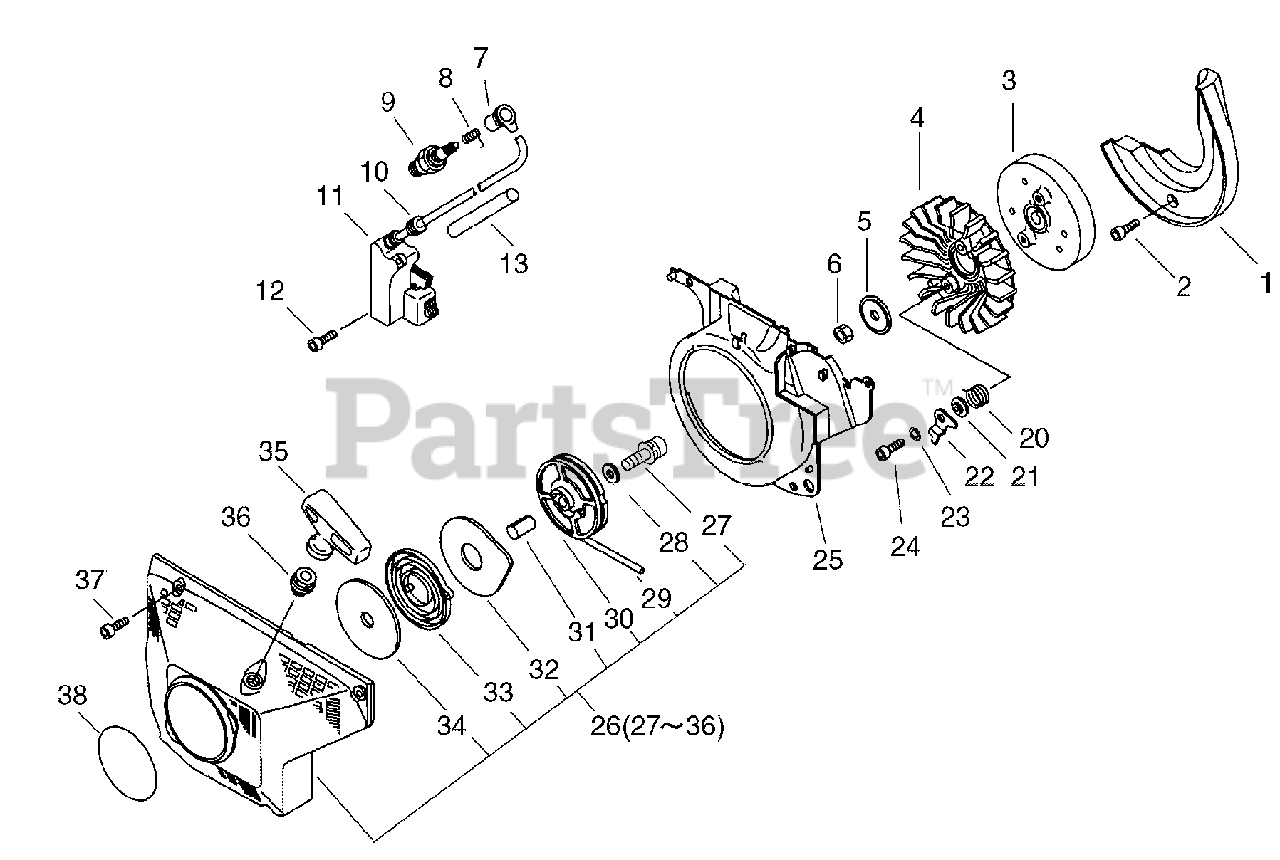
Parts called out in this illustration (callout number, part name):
1	SHIELD, FAN
2	SCREW - 5X20
3	FLYWHEEL
5	WASHER - CUP
6	NUT - 8 -- FLANGE
7	CAP, SPARK PLUG
8	TERMINAL, SPARK PLUG CAP
9	SPARK PLUG -- RCJ-6Y
11	COIL, IGNITION
12	SCREW - 4X20
20	SPRING, RETURN
22	PAWL, STARTER
23	WASHER - 5
24	SCREW - 5X30
25	SHIELD, FAN
26	STARTER ASSY
27	SCREW - 5X14
28	WASHER - 5
29	ROPE, STARTER - 4X950
30	REEL, ROPE
32	PLATE, STARTER
33	SPRING, REWIND
34	PLATE, STARTER
35	GRIP, STARTER
36	GUIDE, ROPE
37	SCREW - 5X20
38	LABEL - ECHO
